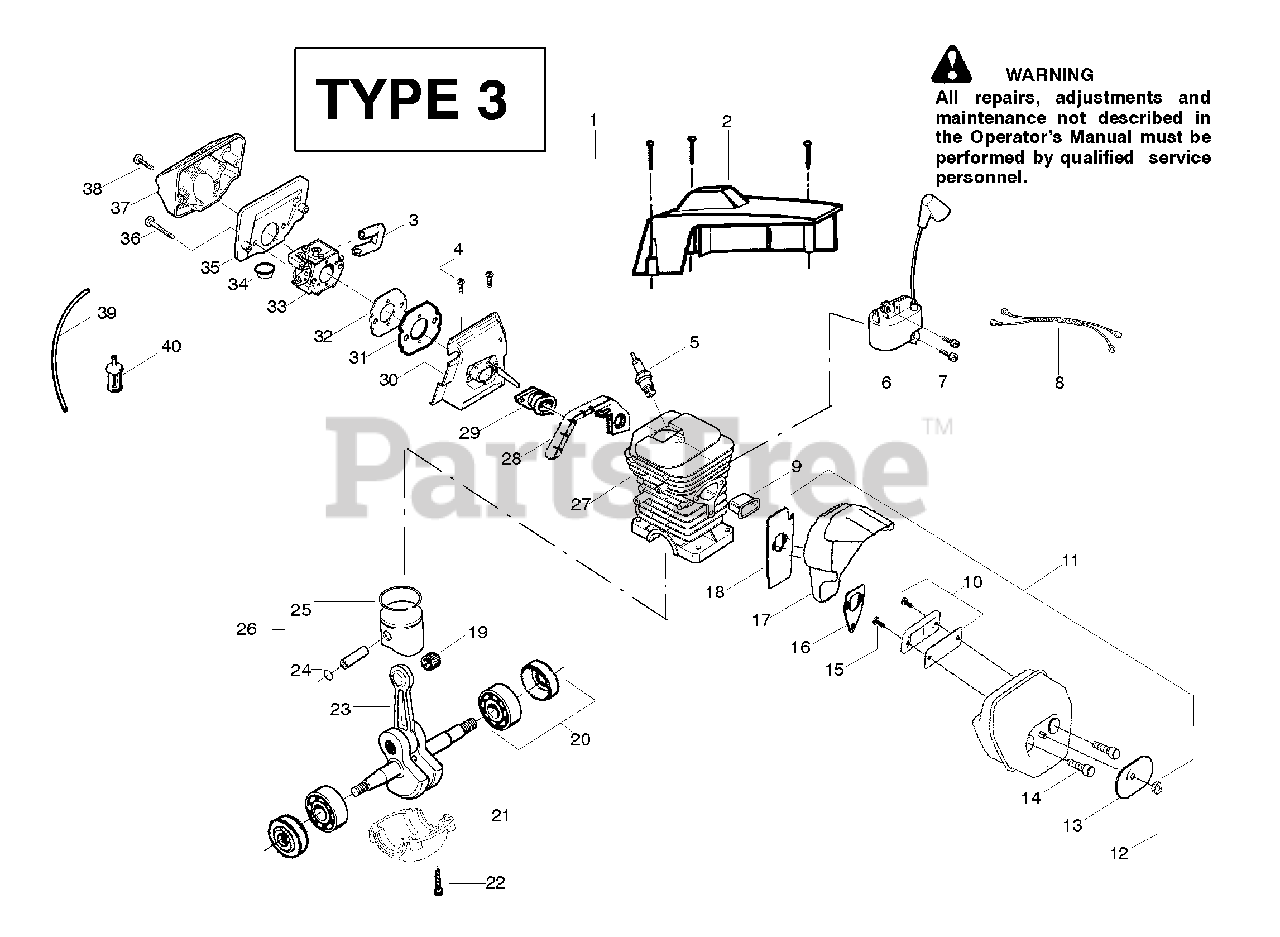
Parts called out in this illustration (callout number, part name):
2	Kit-Cylinder Shield
3	Grommet -Carb.
5	Spark Plug
6	Module-Ignition
8	Assy-Switch Wire
9	Insulator-Heat
10	Kit-Spark Arrestor
11	Kit-Muffler
12	Nut-Brass
13	Cover-Bolt
14	Bolt-Muffler
15	Screw-Spark Screen
16	Gasket-Muffler
17	Assy-Muffler Backplate
18	Backplate - Alum.
20	Assy-Bearing & Seal
21	Cap-Crankcase
23	Assy-C'shaft & Rod
24	Retainer-Piston Pin
25	Ring-Piston
26	Kit-Piston
27	Assy-Cyl/Crankcase
28	Seal-Super Clean
29	Intake Boot
30	Adapter-Carb.
31	Intake Plate-Carb
32	Gasket-Carb.
33	Kit-Carburetor
34	Isolator
35	Filter-Air
37	Filter-Air
39	Kit-Fuel Line
40	Assy-Fuel Pick-up
